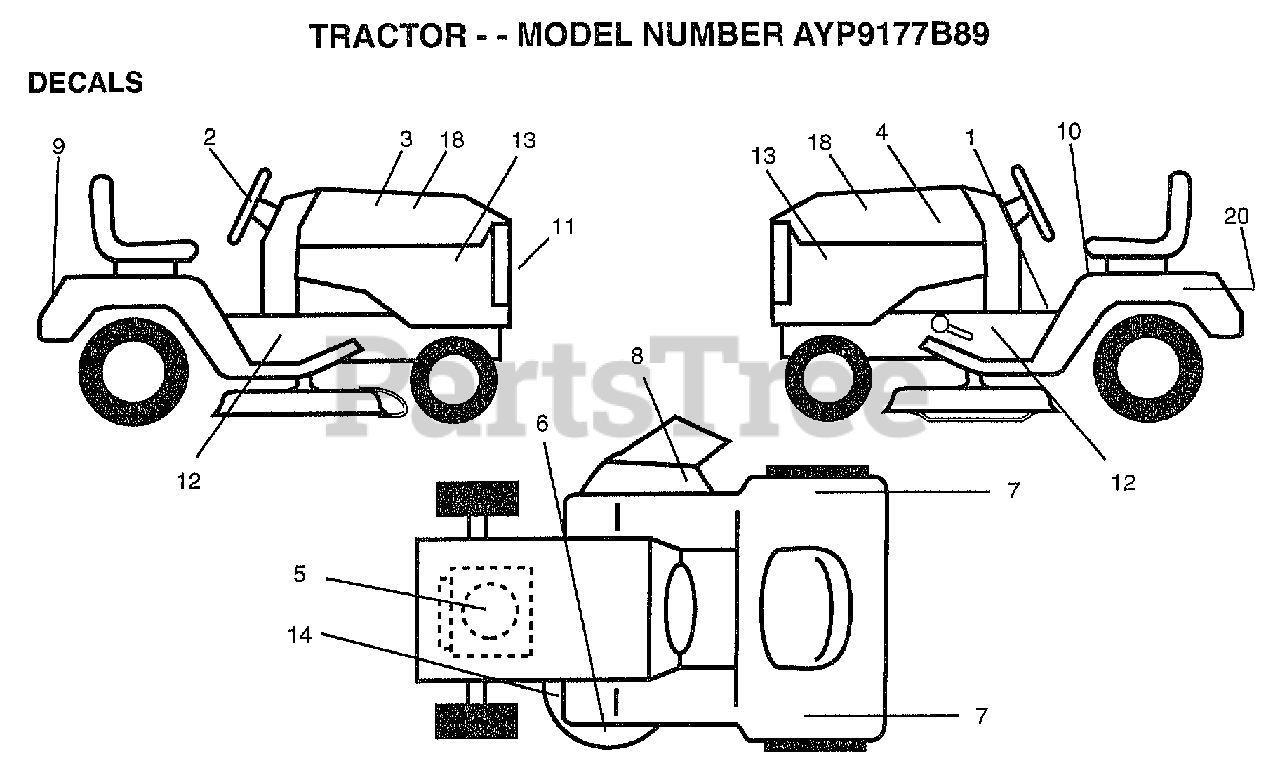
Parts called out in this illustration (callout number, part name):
1	"DEAL-OPER,INST."
2	DECAL STEER WHL
3	DECAL HOOD RH
4	DECAL HOOD LH
5	DECAL, HP ENGINE
6	DECAL DECK MULCH
7	DECAL.FENDER.AUTO
8	DECAL DECK WIZ +
10	"DECAL DANGER,FEND"
11	DECAL.LENS.WIZARD
12	"DECAL.CHASSIS.42"""
13	DECAL.SIDE PANEL
14	"DECAL-SCHEM,BELT"
18	NAMEPLATE.HD.WIZA
20	DECAL.BATRY.3-3908
